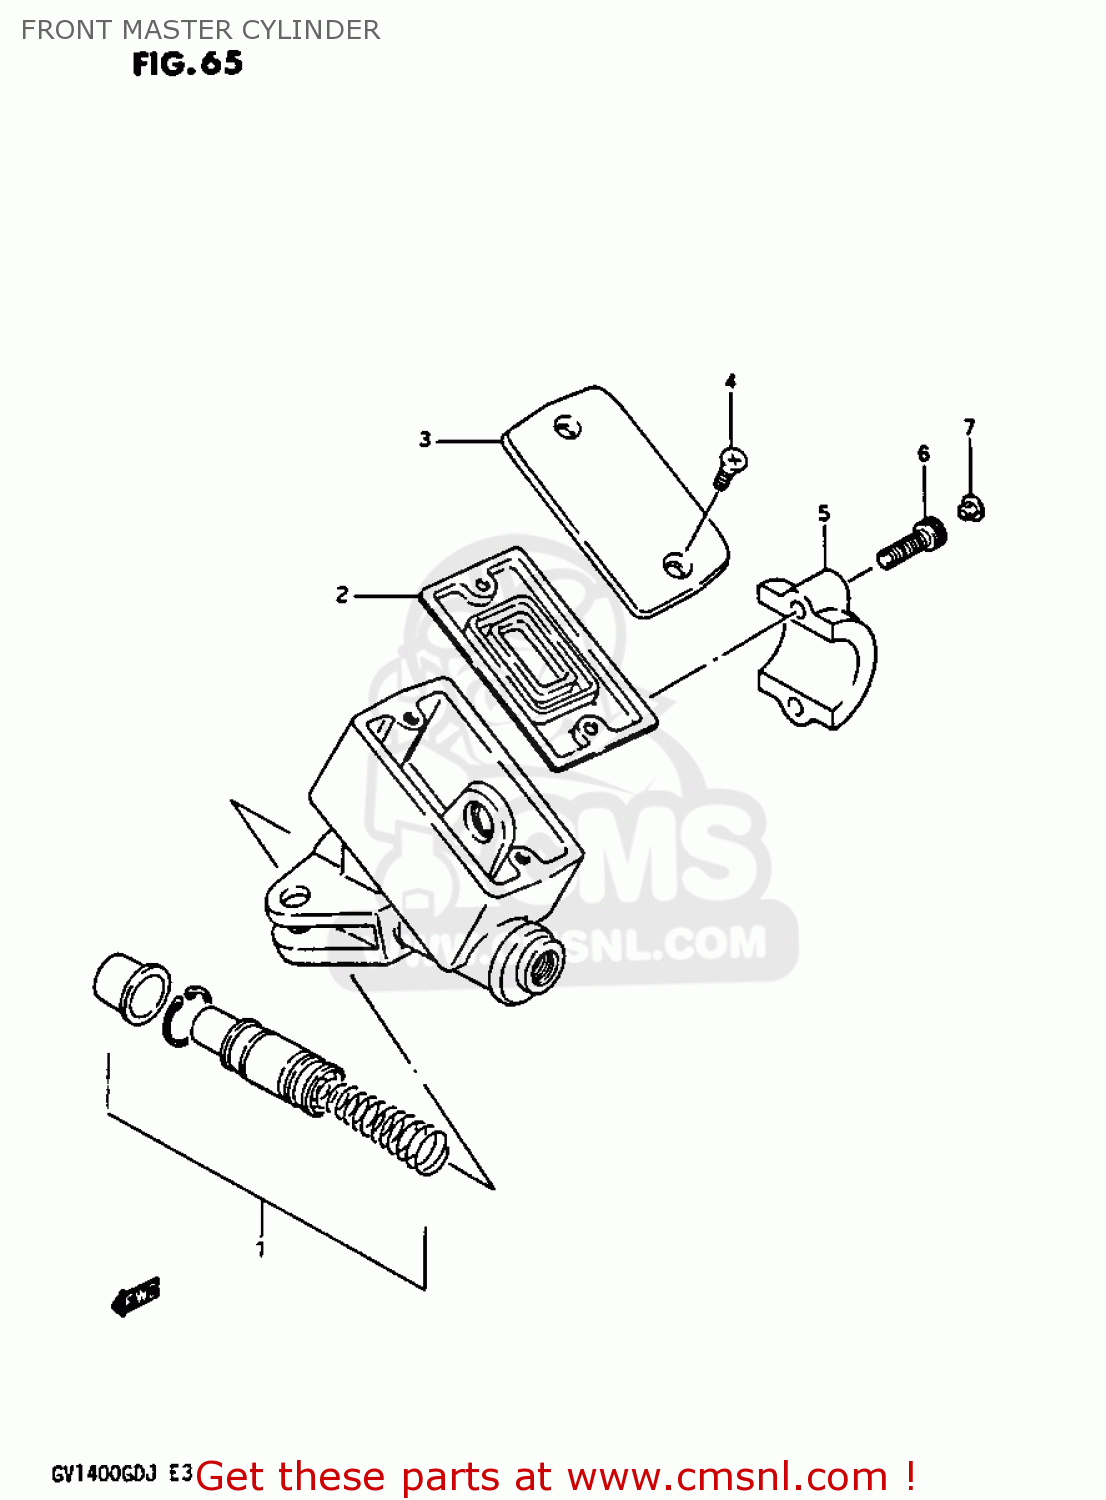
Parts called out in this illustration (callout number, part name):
1	PISTON & CUP SET
2	3
3	CAP
4	SCREW
5	HOLDER,MASTER CYLINDER
6	BOLT
7	CAP(OD:10)
